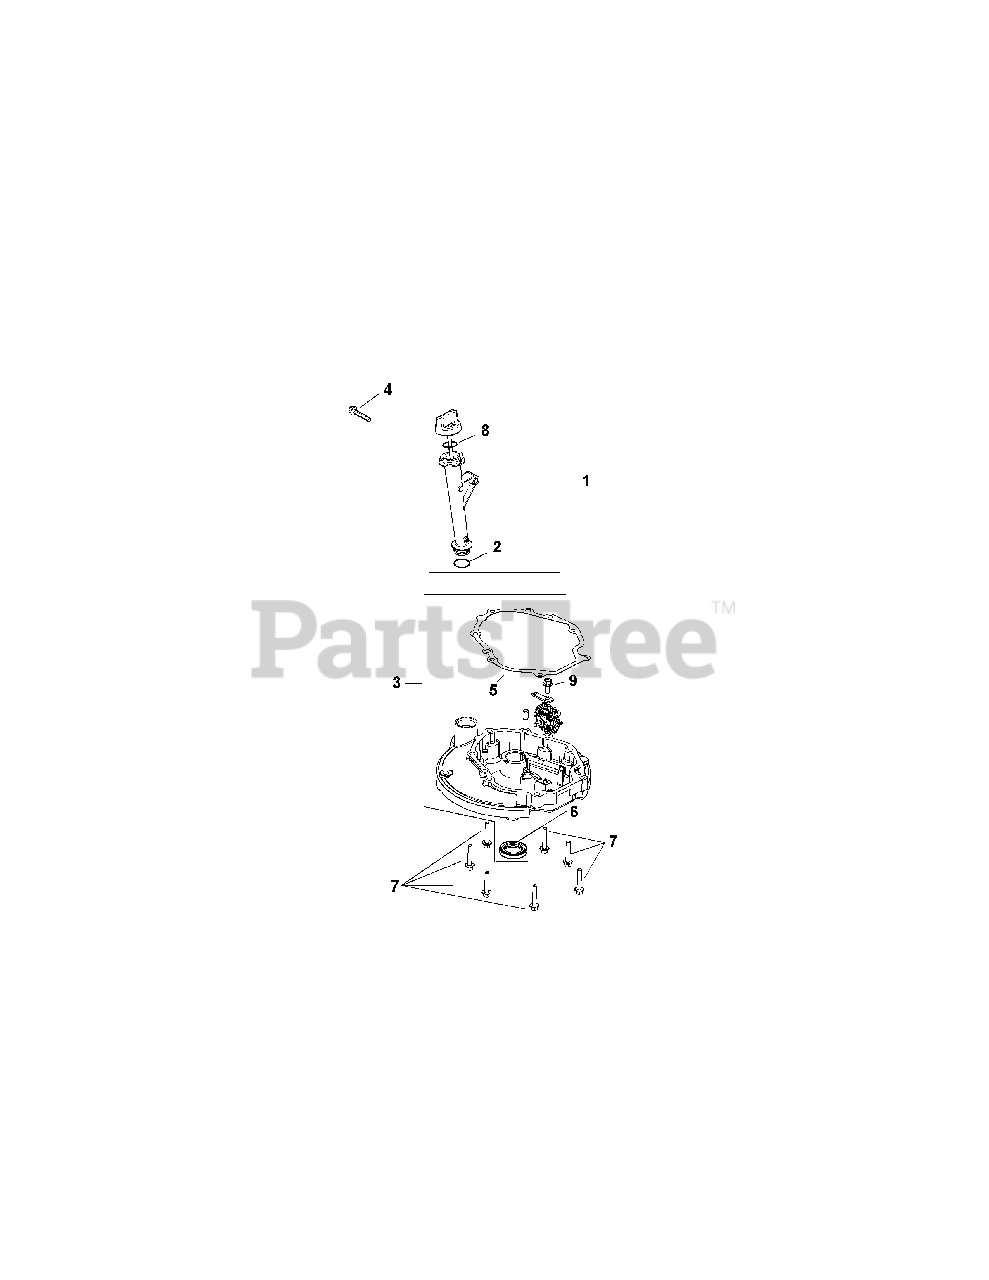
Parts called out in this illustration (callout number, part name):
1	Oil Fill Tube Assembly
2	Oil Fill Tube O-Ring
3	Oil Pan Kit
4	Hex Flange Screw, M6
5	Oil Pan Gasket
7	Hex Flange Screw, M8
9	Hex Flange Screw, M6
